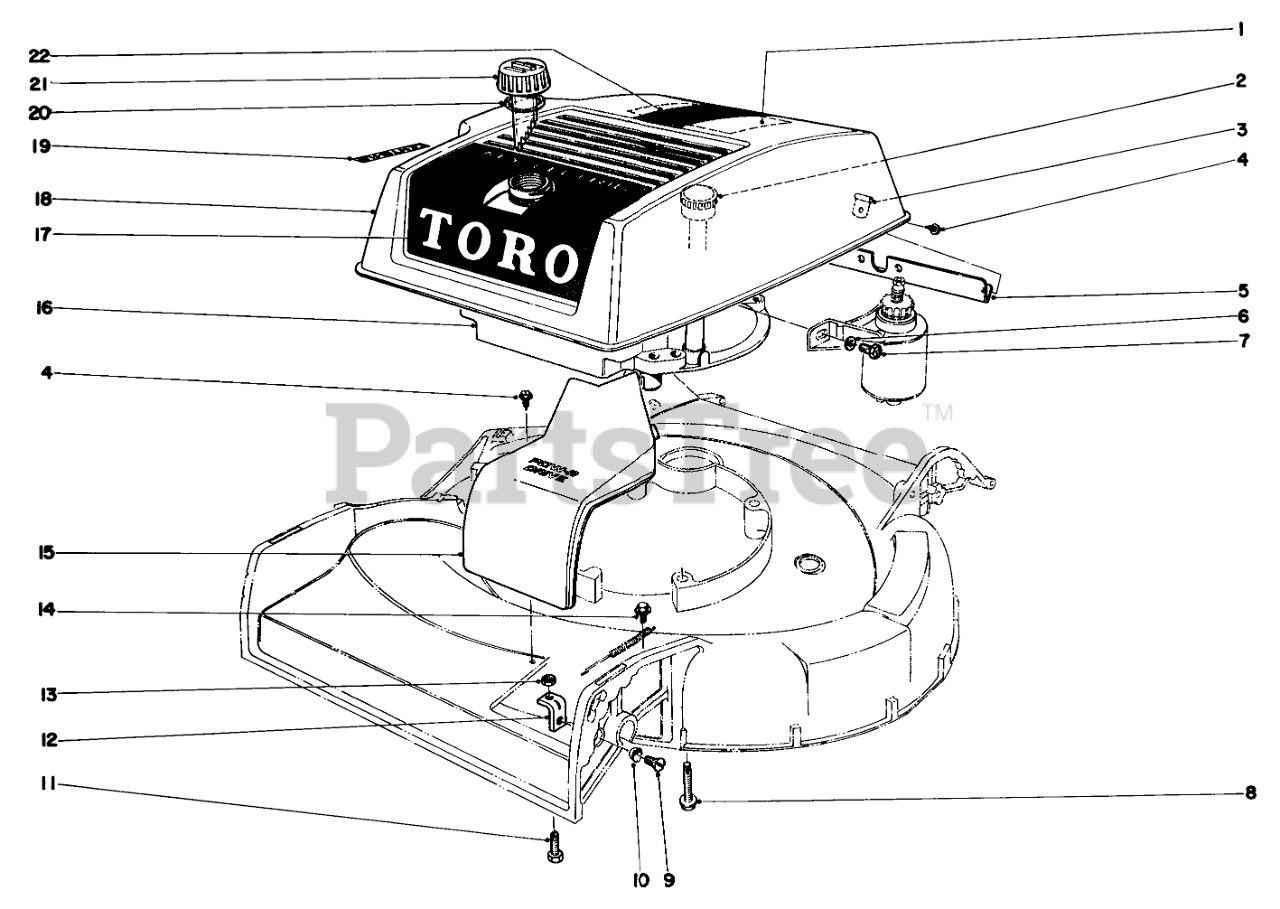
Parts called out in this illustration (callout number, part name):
1	Decal-Maintenance
2	Dip Stick
3	Hinge
4	SCREW-HWHTF
5	Shroud Bracket
6	Washer
7	Screw
8	3/8-16 X 2-3/4 CAPSCR
9	5/16-18X5/8 FLT HD MS
10	Lockwasher
11	SCREW
12	ADJ BRACKET
13	NUT-JAM
14	SCREW-HHF
15	Belt Drive Cover
16	Engine
17	Decal
18	Shroud
19	Decal, Air Cleaner
20	Gasket
21	Gas Cap
22	Decal
